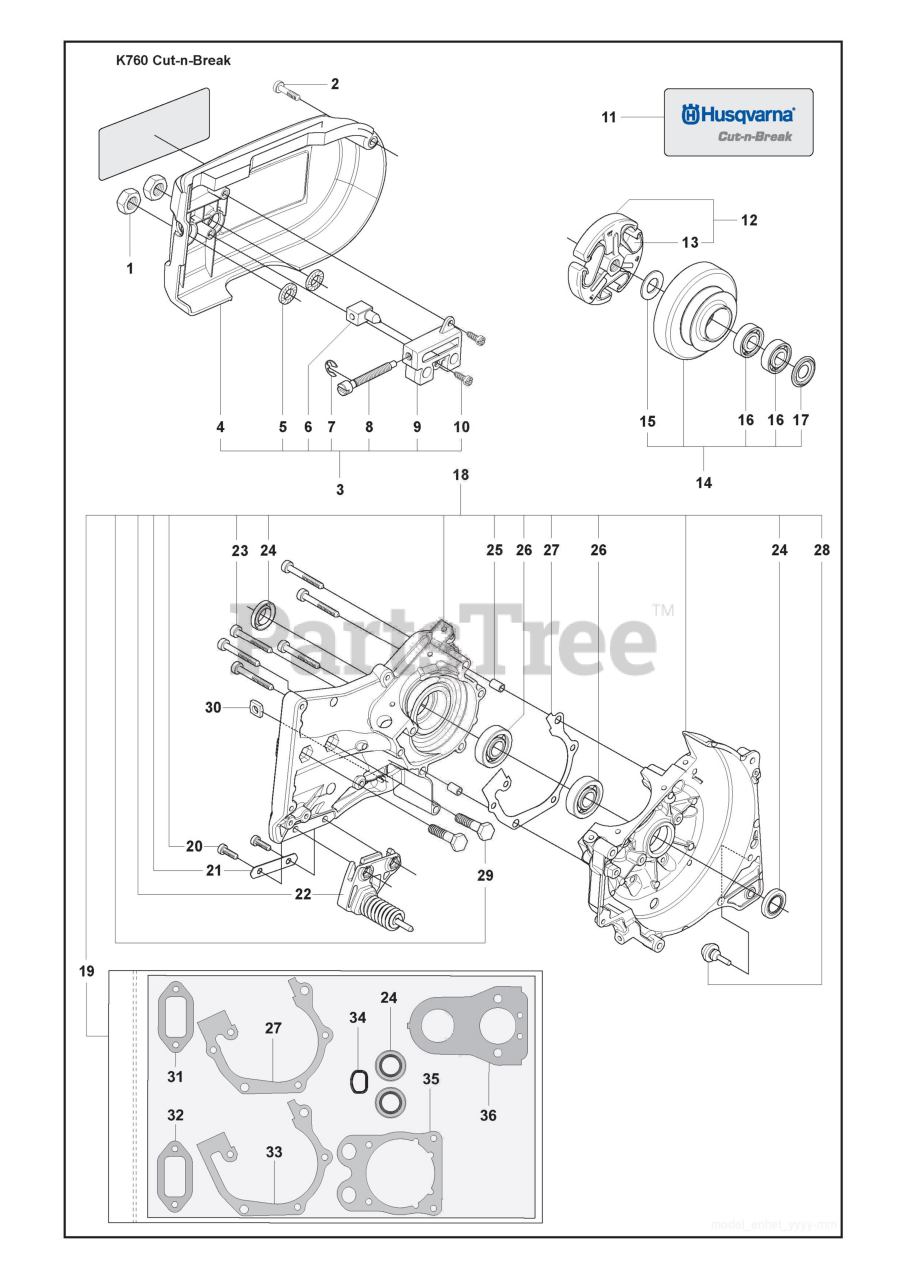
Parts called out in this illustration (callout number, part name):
1	Nut
3	Belt Tensioner Assy
4	Clutch Cover
8	Screw
9	Belt Tensioner
12	Clutch Assy
13	Clutch Spring
14	Driving Pulley Assy
15	Washer
16	Ball Bearing
17	Dust Cover
18	Crank Case Assy
19	Gasket Kit
22	Spring Retainer
24	Sealing Ring
25	Guide Bushing
26	Ball Bearing
27	Gasket Crankcase
32	Gasket Muffler
33	Gasket Crankcase
35	Cylinder Base Gasket
36	Gasket Carburettor
